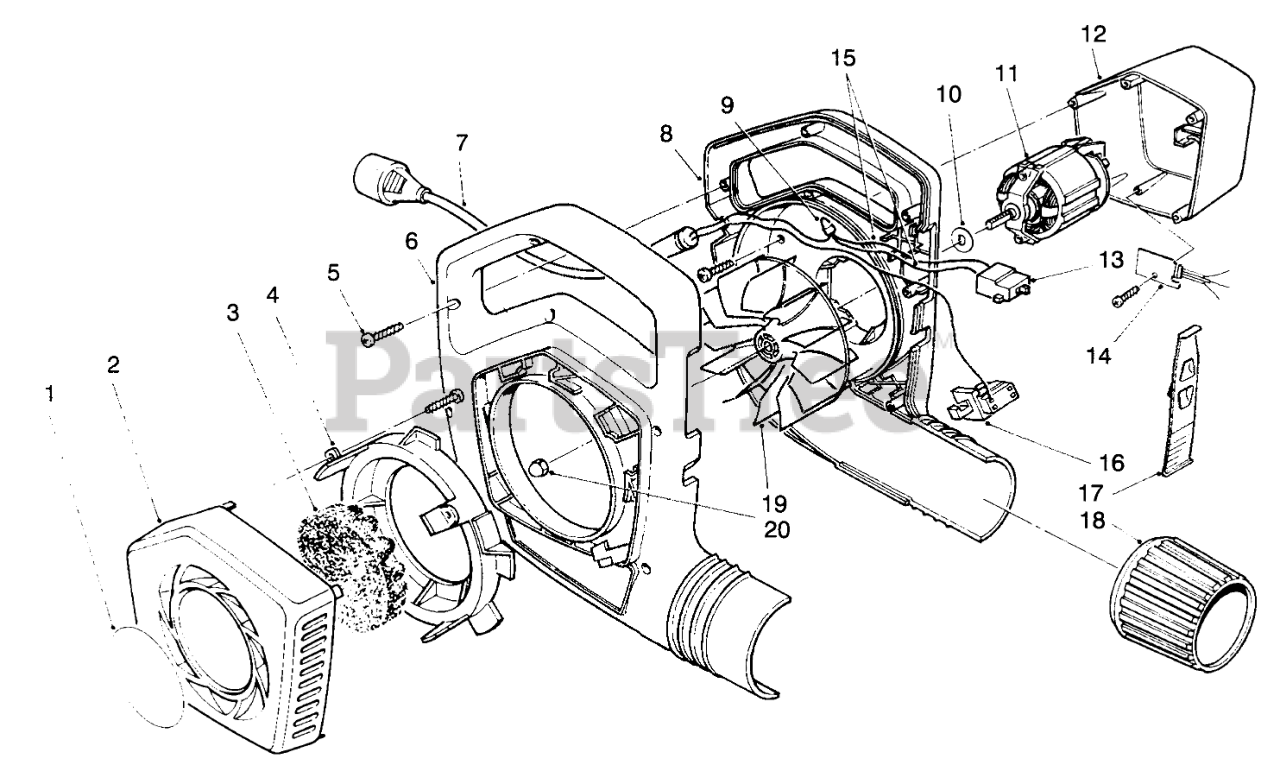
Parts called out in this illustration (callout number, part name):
1	DECAL, COVER
2	INTAKE COVER, 850 BV
3	CENTER FOAM
4	Ring-Coupling
5	Screw
6	Housing-Blower,R.H.
7	POWER SUPPLY CORD 9.5
8	BLOWER HOUSING, LH
9	Connector
10	Washer-Impeller
11	Motor-Blower
12	MOTOR COVER,850 HOTSTAM
13	Switch-2 Speed
14	DIODE ASSEMBLY
15	WIRE, 3 INCH
16	SWITCH-INTERLOCK
17	CAM SWITCH-HOT STAMPED
18	BV-OUTPUT COLLAR
19	IMPELLER, 850 BLOWER
20	NUT-HEX
